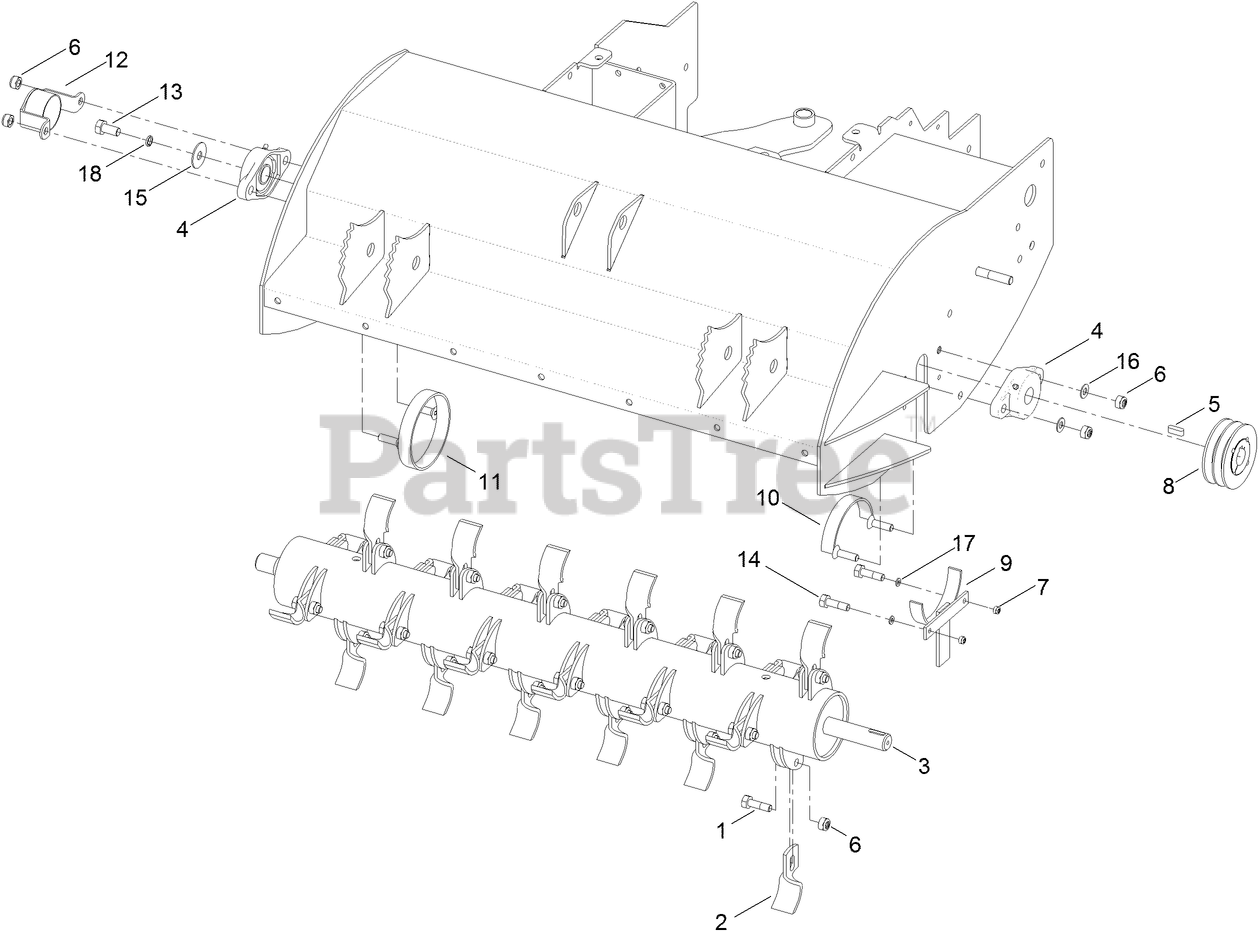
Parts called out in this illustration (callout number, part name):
1	SCREW-HH
2	KNIFE-FLAIL
3	FLAIL ROTOR ASM
4	BEARING-FLANGE
6	NUT-HEX, NI
7	NUT-NYLOC
8	PULLEY-V
9	COLLAR-ROTOR END, LH LOWER
10	COLLAR-ROTOR END, LH UPPER
11	COLLAR-ROTOR END, RH COLLAR
12	COVER-END, ROTOR
13	SCREW-HH
14	SCREW-HH
15	WASHER
16	WASHER-PLAIN
17	WASHER-PLAIN
18	WASHER-LOCK
